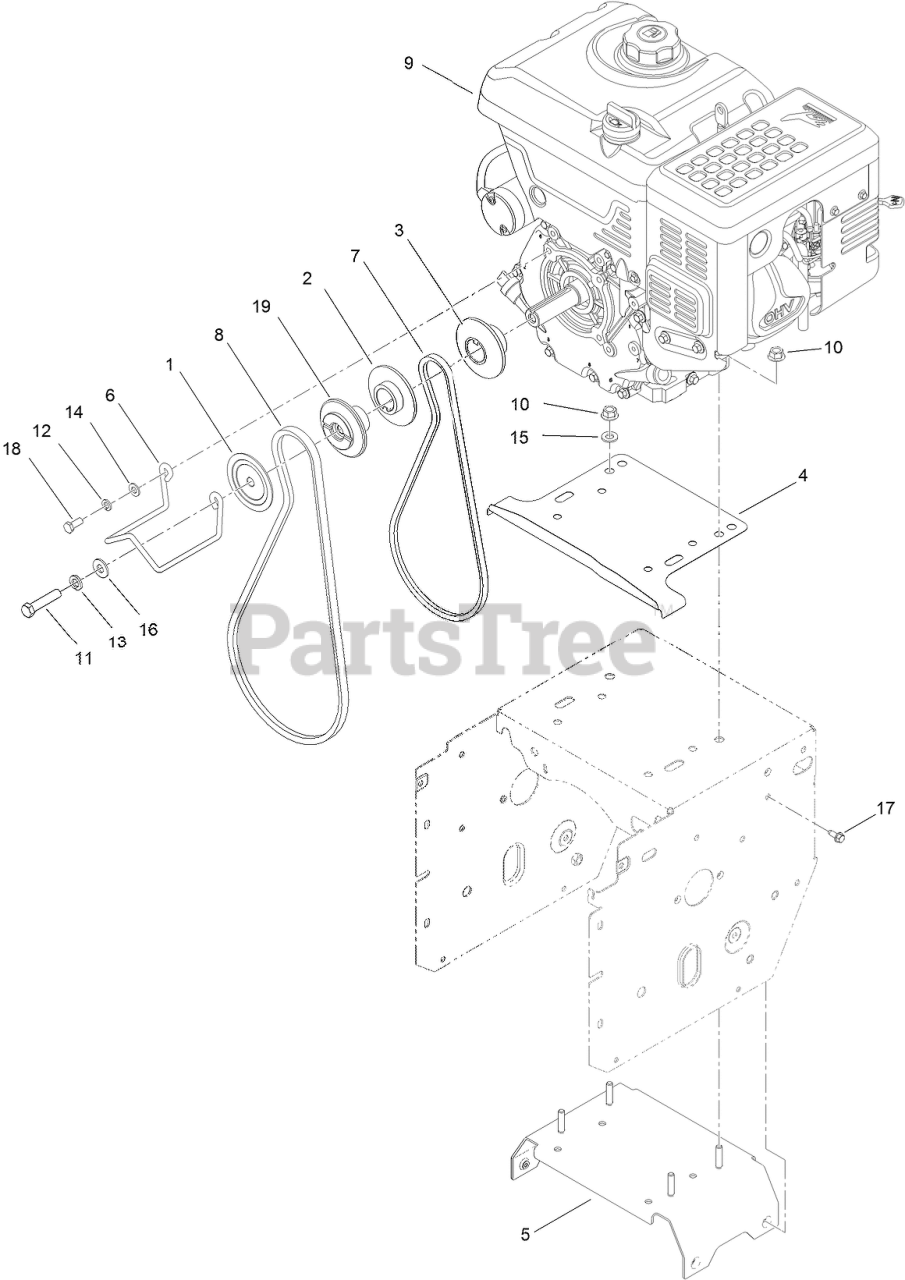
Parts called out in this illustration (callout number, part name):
1	SHEAVE-HALF, IMPELLER
2	PULLEY-ENGINE, TRACTION
3	SHEAVE-HALF, TRACTION
4	SHIELD-DRIVE
5	FRAME BRACE ASM
6	GUIDE-BELT
7	BELT-V
8	BELT-V
9	ENGINE-175FDS-1
10	NUT-FLANGE
11	SCREW-HH
12	WASHER-LOCK
13	WASHER-LOCK
14	WASHER-PLAIN
15	WASHER-FLAT
16	WASHER-FLAT
17	SCREW-HWH
18	SCREW-HH
19	PULLEY-ENGINE, IMPELLER
